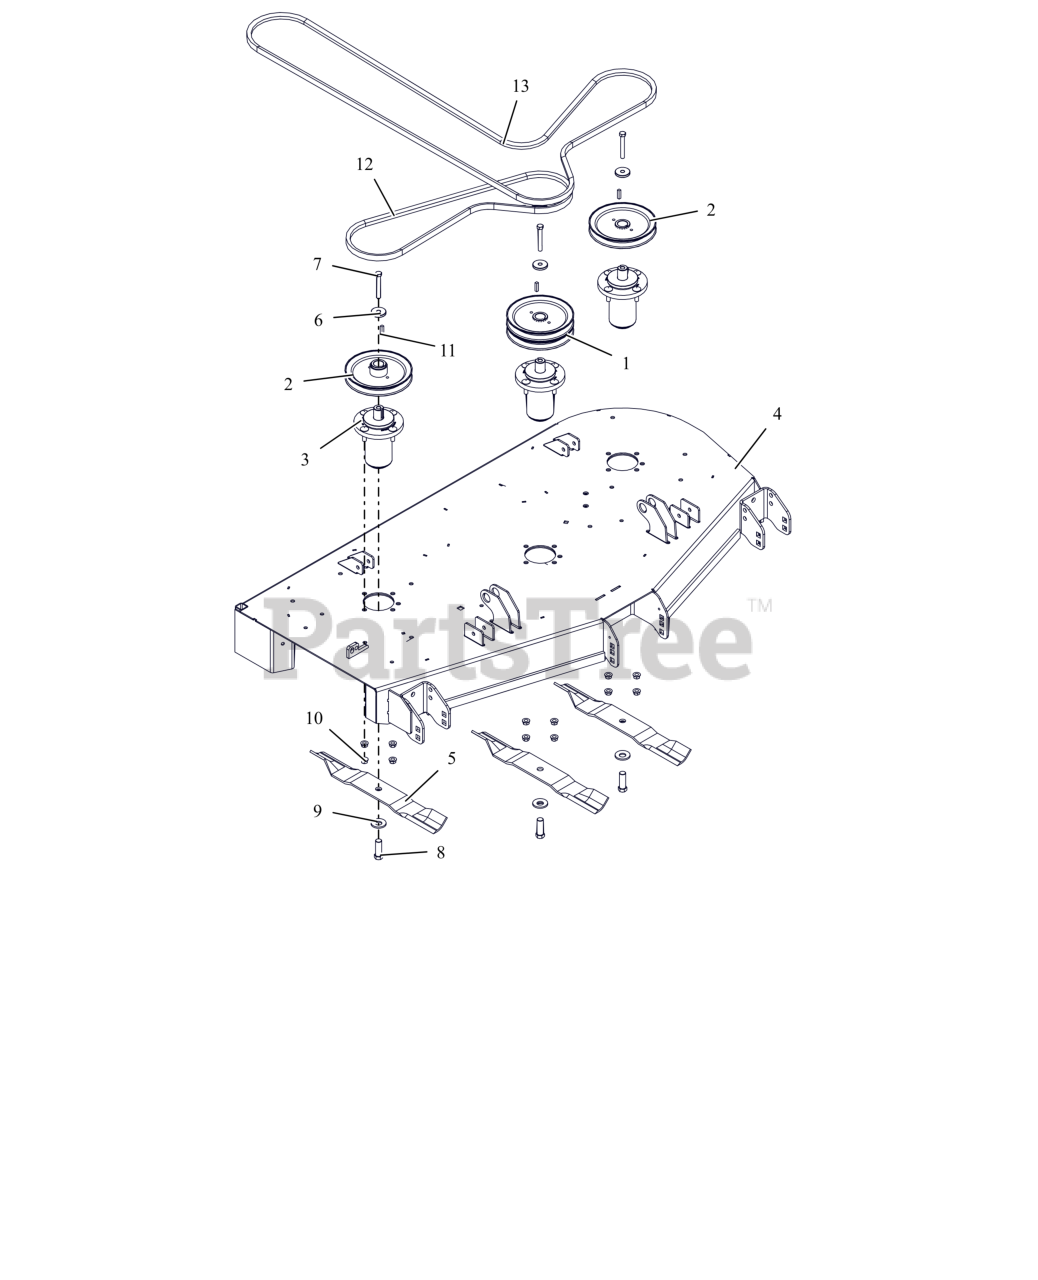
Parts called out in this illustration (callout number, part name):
1	PULLEY, DOUBLE-1"ID X 6.75"OD
2	PULLEY, V-1" ID X 6.75" OD
3	ASM, MAINT FREE ALUM SPINDLE
4	KIT,DECK-52" W/DECALS - ARIENS
5	BLADE, 18"
6	RETAINER, SHEAVE
7	BLT, HEX .38-16X2.75 G8 ZCC
8	BLT, HEX .62-18X1.75 G8 ZCC
9	WSHR-BLVL .669X1.535X.138
10	NUT-LK-CTR-FLG .375-16 GF ZCC
11	KEY, SQ .25X.25X1.00 RC 40-50
12	V-BELT, B-COGGED
13	V-BELT, HB SECTION
